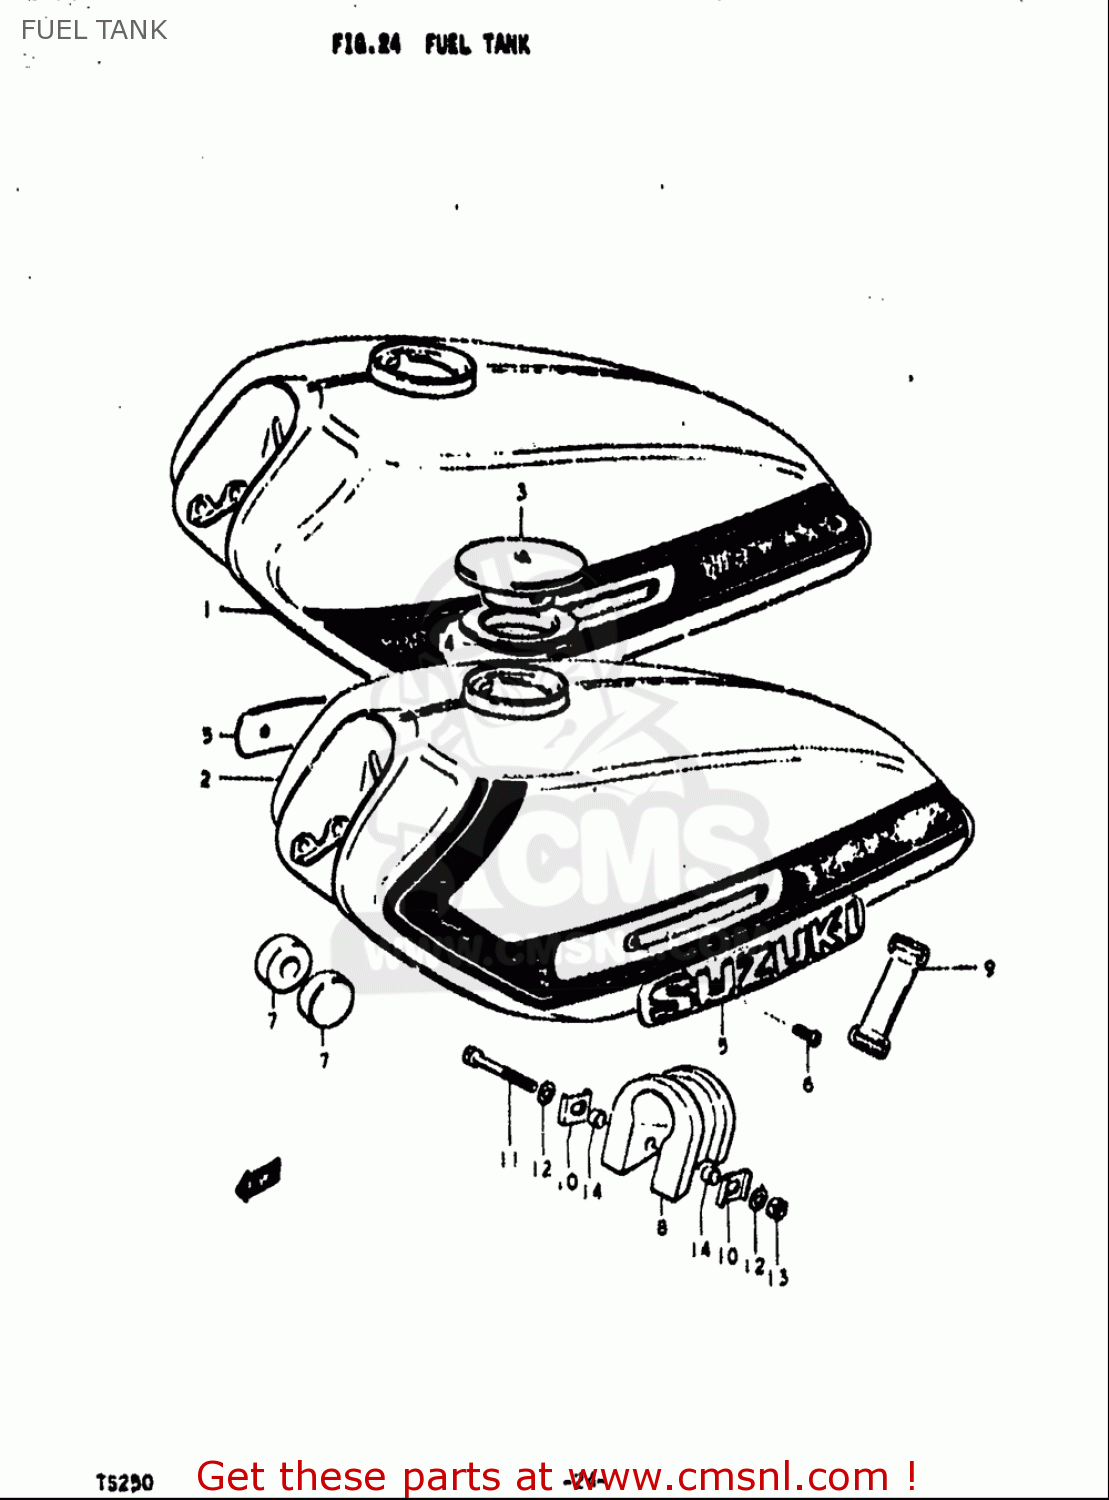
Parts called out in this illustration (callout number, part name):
6	SCREW
7	CUSHION
11	BOLT
12	WASHER
13	NUT
14	SPACER(6.1X8X5.2)
